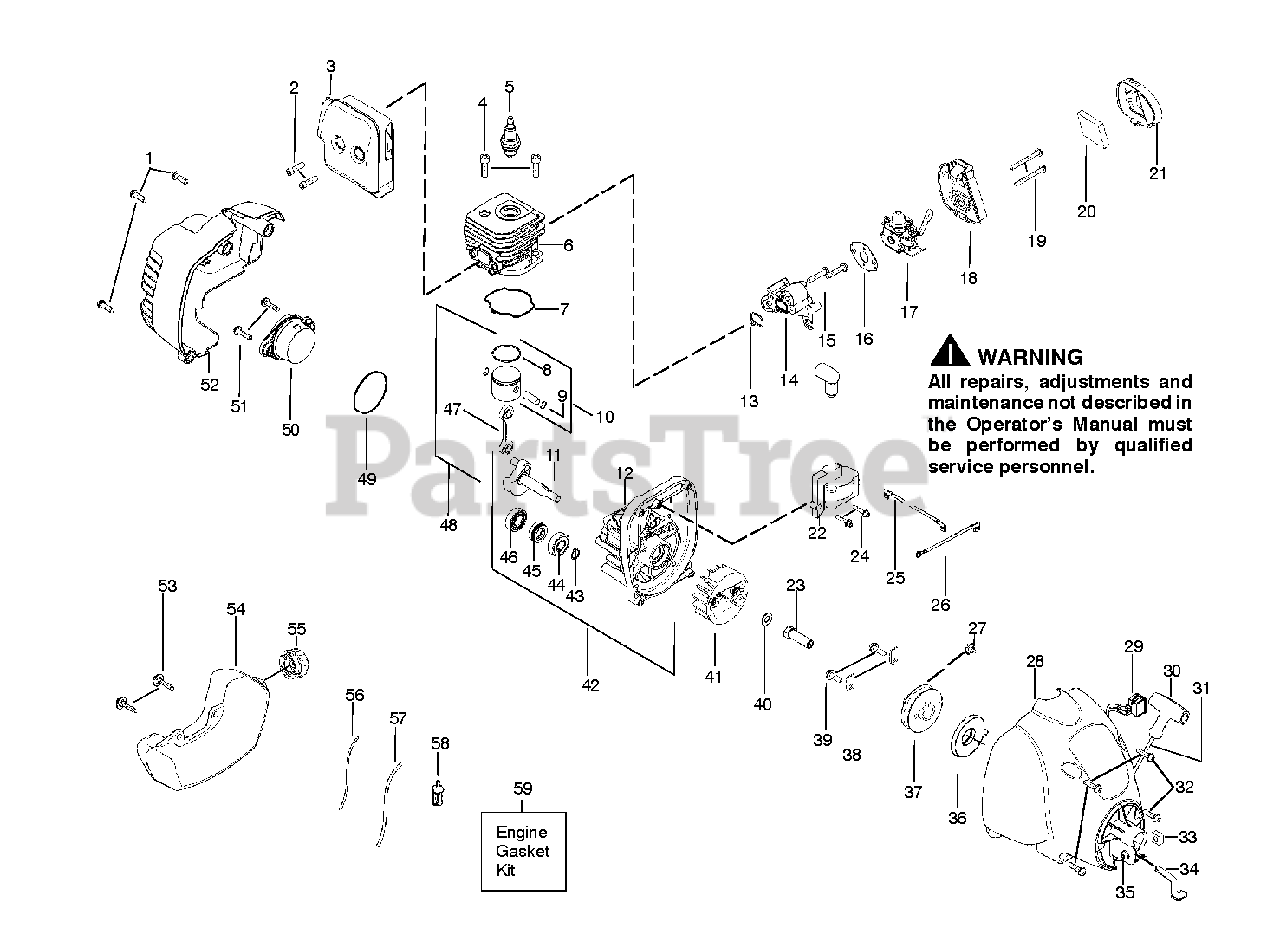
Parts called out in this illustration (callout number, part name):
2	BOLT MUFFLER
3	ASSY MUFFLER SHIELD
5	PLUG-SPARK (RCJ-6Y)
6	CYLINDER MACHINED 25CC LO
8	RING PISTON
9	WRIST PIN RET.
10	PISTON
11	ASSY CRANKSHAFT
12	ASSY CRANKCASE
14	ADAPTOR CARBURETOR
17	KIT CARB ASSY #C1U-W18
17	KIT CARB ASSY WT924
18	BASE AIRBOX
20	FOAM AIR FILTER
21	COVER AIR BOX
23	DRIVE-COUPLING
25	LEAD WIRE
26	GROUND WIRE
27	SCREW SEMS TOOTHED WASHER
28	HSG FAN W/EYELET
29	KIT SWITCH MOMENTARY
30	HANDLE-STARTER
31	KIT ROPE
33	NUT SQUARE
36	STARTER SPRING
37	STARTER PULLEY KIT
38	RETAINER
39	SCREW 8-16 X 9/16 (PLAS
40	WASHER FLAT
41	ASSY FLYWHEEL
42	ASSEMBLY
43	RETAINING RING
44	OUTER BEARING
46	BEARING
47	KIT-CONN ROD ASSY
48	PISTON KIT
50	ASSY REAR PLUG
52	CYLINDER COVER
53	SCREW FUEL TANK RETAINER
54	FUEL TANK ASSY
55	CAP ASSY W/ RETAINER
56	KIT-LINE
57	LINE KIT
58	FUEL PICK-UP ASSY
59	KIT GASKET 25CC
